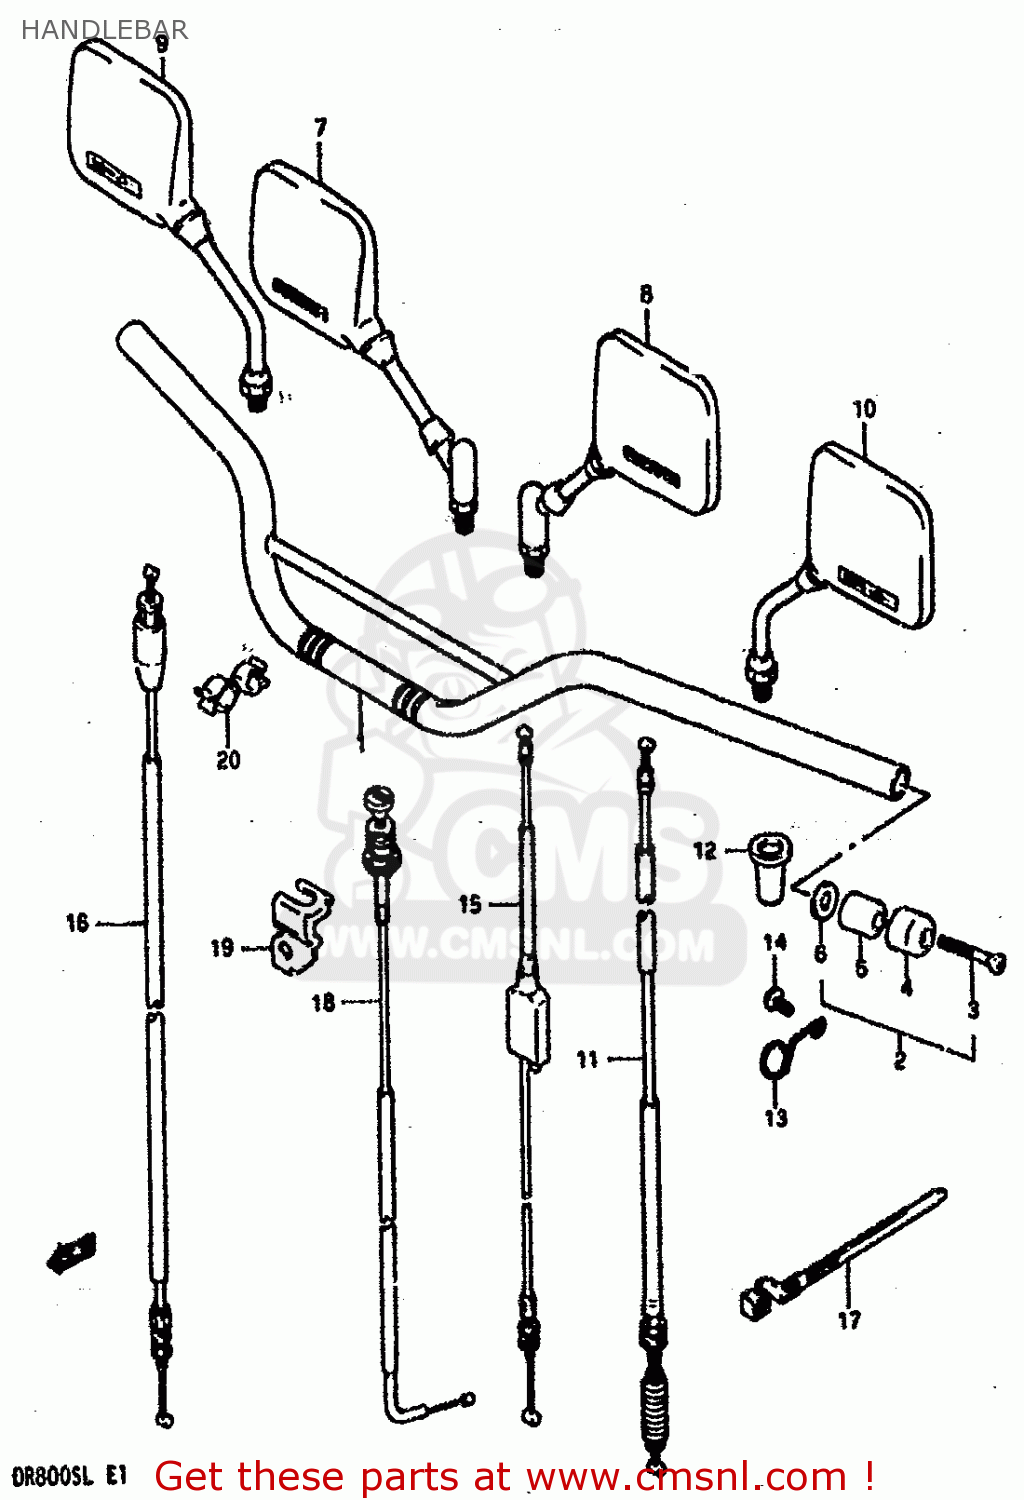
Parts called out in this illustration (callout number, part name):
1	HANDLEBAR (SILVER)
2	BALANCER SET,HANDLEBAR
3	SCREW
4	CAP,HANDLE BALANCER
5	BALANCER,HANDLEBAR
6	SPACER,BALANCER
7	MIRROR ASSY,REAR VIEW RH
8	MIRROR ASSY,REAR VIEW LH
9	MIRROR ASSY,REAR VIEW RH
10	MIRROR ASSY,REAR VIEW LH
11	CABLE ASSY,CLU
12	BOOT,CLUTCH CABLE
13	CLIP
14	SCREW
15	CABLE ASSY,DECOMPRESSION
16	CABLE ASSY,THROTTLE
17	CLAMP, CABLE
18	CABLE ASSY,STARTER
19	BRACKET,STARTER CABLE
20	CLIP
